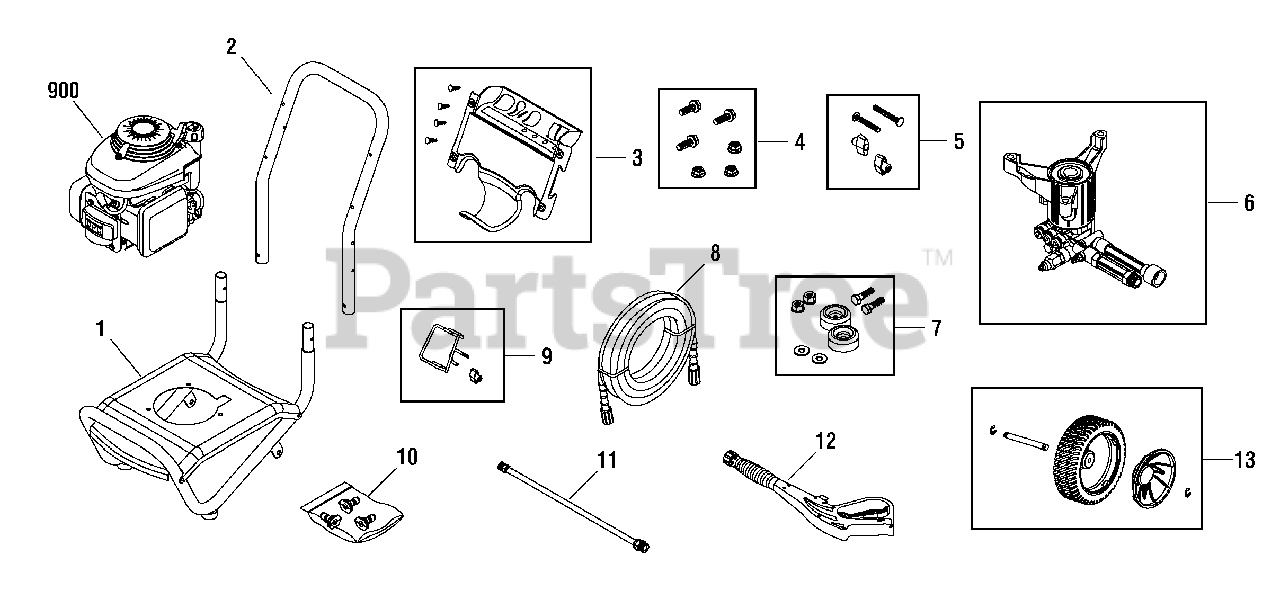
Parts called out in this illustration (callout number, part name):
2	HANDLE
3	KIT, Billboard w/Decals & Clips
4	KIT, Pump Mounting Hardware
5	KIT, Handle Connector
6	PUMP ASSEMBLY
7	KIT, Vibration Mount
8	HOSE
9	KIT, Gun Holder
11	EXTENSION
12	GUN
13	KIT, Wheel
900	* ENGINE
